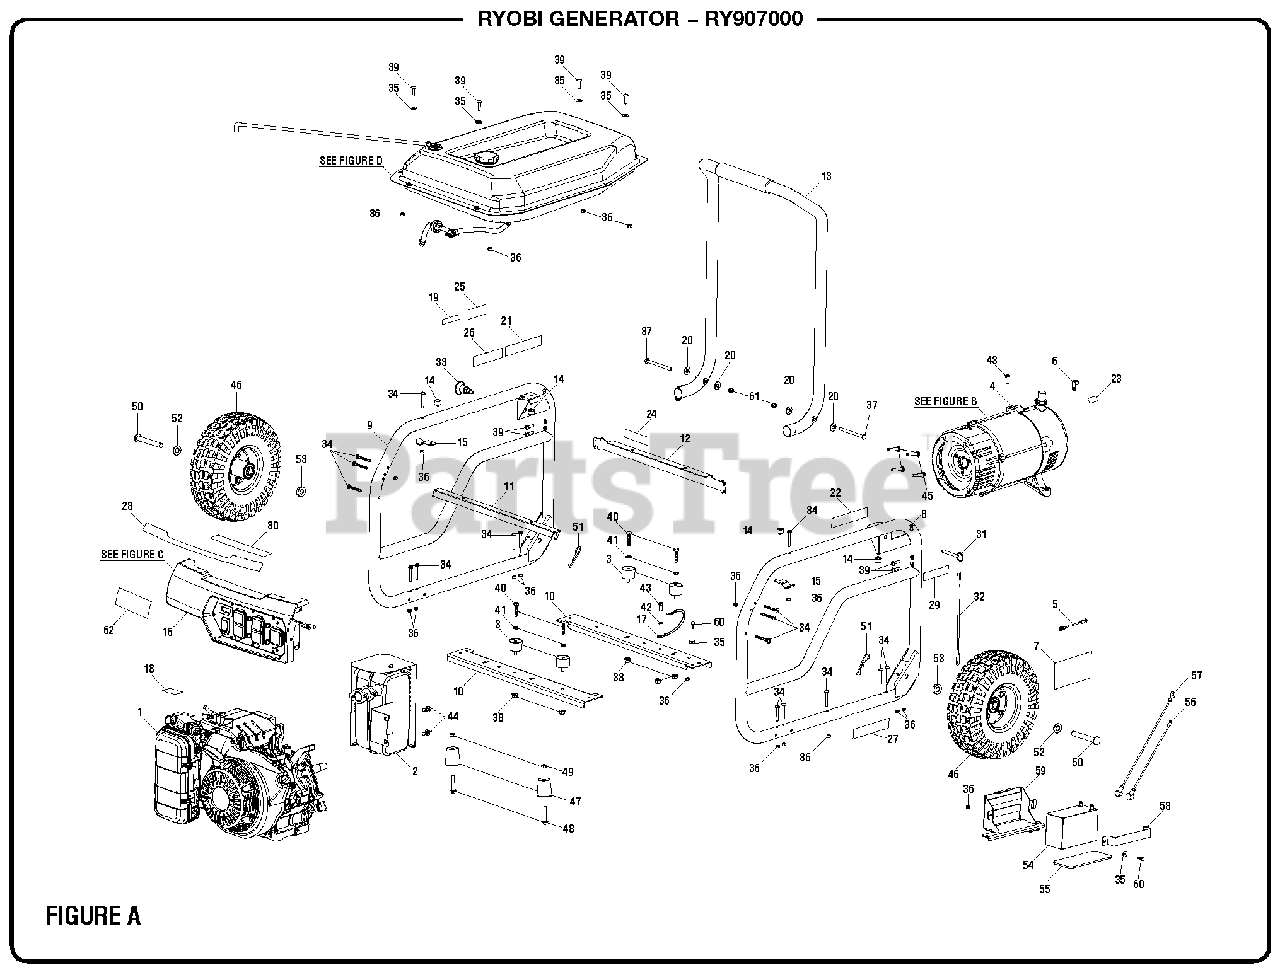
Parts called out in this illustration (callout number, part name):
1	Engine (Honda)
2	Muffler Assembly
4	Generator Head Assembly (See Figure B)
5	Bonding Wire
6	Ground Lug
7	Rubber Sheet
8	Frame Assembly (Right)
9	Frame Assembly (Left)
10	Cross Bar
11	Fuel Tank Support (Front)
12	Fuel Tank Support (Rear)
13	Handle Assembly
14	Handle Bumper
15	Handle Rest Tab
16	Control Panel Assembly (See Figure C)
17	Ground Wire Assembly
18	Choke Label
19	Inquiries Label
21	Fire Distance Label
22	Fire Danger Label
23	Ground Label
24	Ground Warning Label
25	Pull Pin Release Label
26	Hot Surface Label
27	Lubricant Label
28	Performance Label
29	Lock Pin Label
30	Quick Start Label
31	Release Pin
33	Handle Lock Assembly
34	Bolt (M6 x 50 mm, Torx Pan Hd. T30)
35	Washer (M6)
36	Lock Nut (M6)
37	Bolt (M8 x 98 mm, Flat Hd.)
38	Lock Nut (M8)
39	Bolt (M6 x 25 mm, Torx Pan Hd.)
40	Bolt (M8 x 35 mm, Hex Hd.)
41	Washer (M8)
42	Star Washer (M8)
43	Bolt (M8 x 15 mm, Hex Hd.)
44	Bolt (5/16-24 x 0.6 in.)
45	Bolt (3/8-16 x 1 in.)
48	Bolt (M8 x 45 mm, Hex Hd.)
49	Lock Nut (M8 x 1.25)
51	Hitch Pin
52	Washer (M10)
54	Battery
55	Battery Tray Gasket
56	Battery Cable (Red)
57	Battery Cable (Black 390 mm)
58	Battery Bracket
59	Battery Tray
60	Bolt (M6 x 16 mm, Hex hd.)
61	Nut (5/16-18 mm)
62	Honda Ryobi Label
